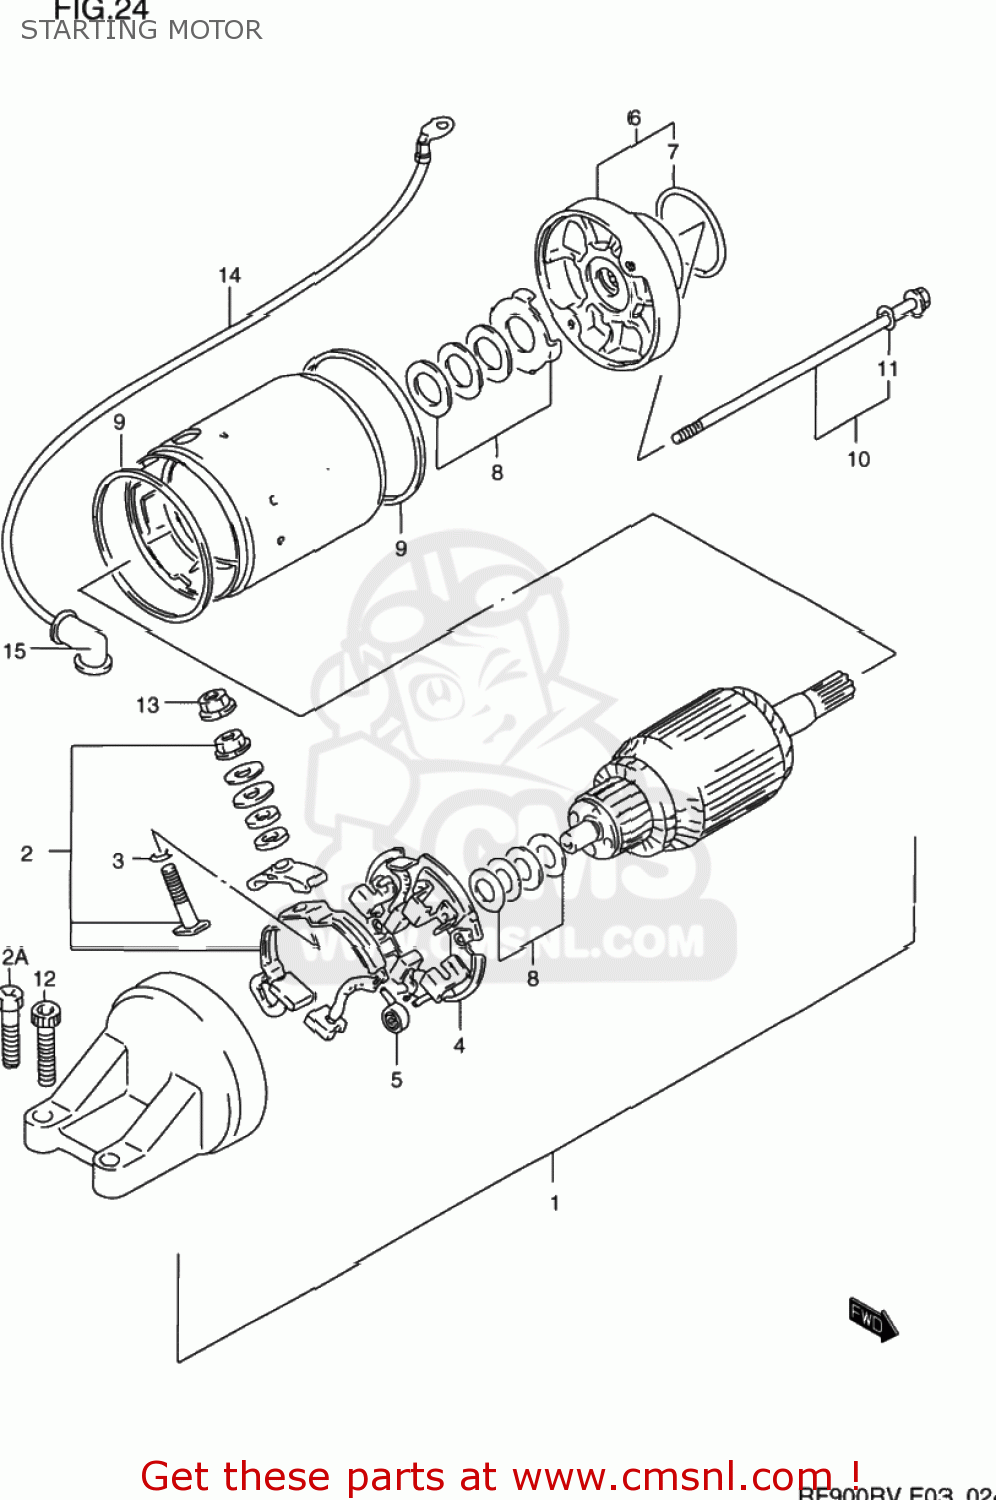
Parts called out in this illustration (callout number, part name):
1	MOTOR ASSEMBLY,STARTING
2	TERMINAL SET,BRUSH,PLUS
3	O RING
4	BRUSH,HOLDER SET
5	SPRING,BRUSH
6	BRACKET ASSEMBLY,FRONT
7	O-RING
8	SHIM SET,STARTING MOTOR
9	O RING
10	BOLT SET,STARTING MOTOR
11	O RING
12	BOLT,OIL PAN
12A	SCREW (6X25)
13	NUT
14	WIRE,STARTER MOTOR LEAD
15	CAP,STARTER MOTOR LEAD
